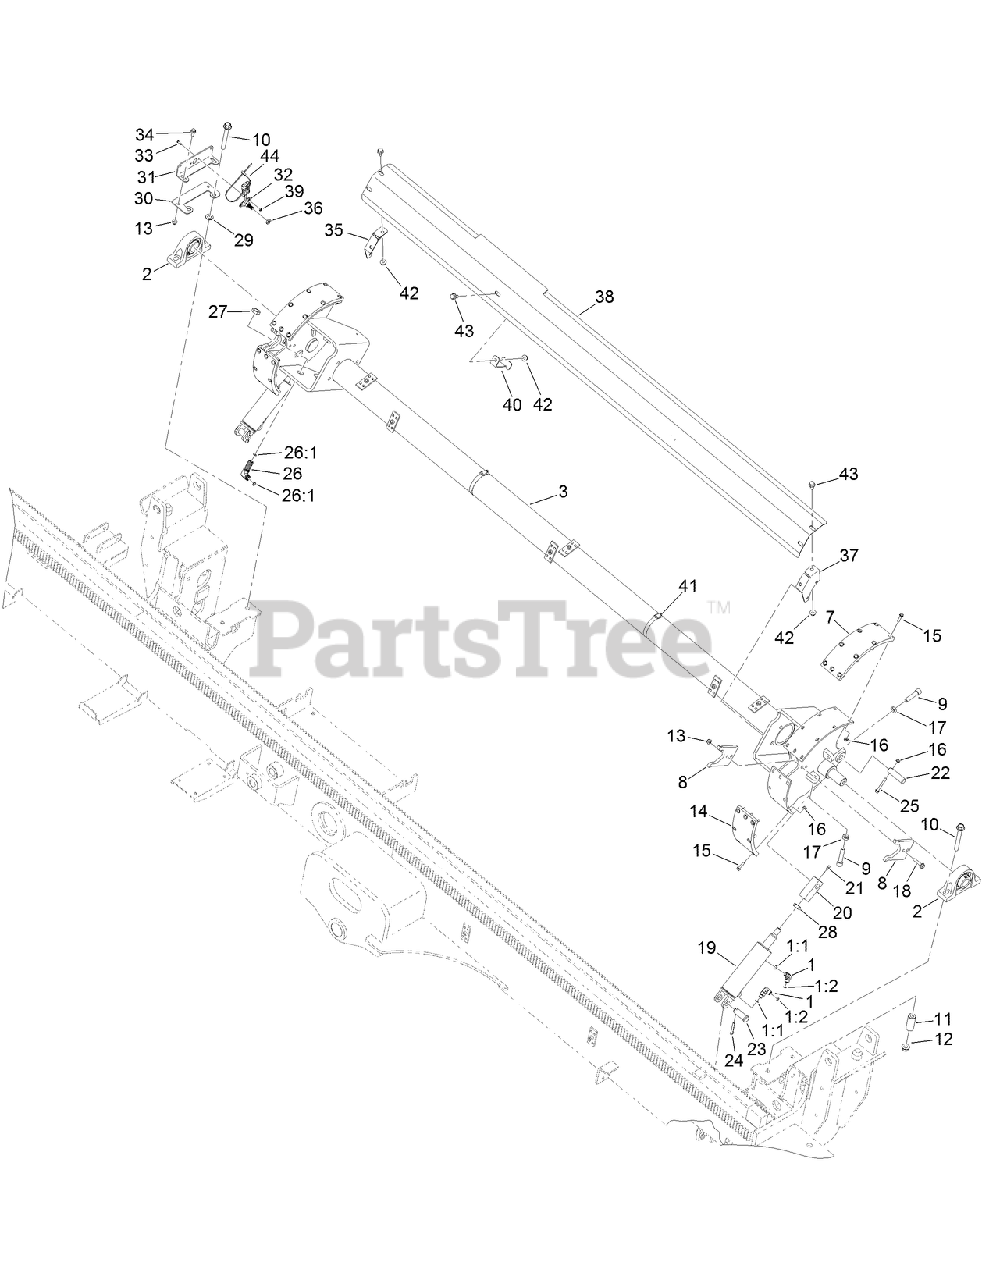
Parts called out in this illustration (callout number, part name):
1	FITTING-ELBOW, 90 DEG
1:1	O-RING
1:2	O-RING
2	BEARING-PILLOW
3	LOADER-ROD, CAM
7	PAD-WEAR, ROD LOADER
8	PLATE-GUIDE, PIPE
9	SCREW-HSH
10	SCREW-HHF
11	SPACER
12	NUT-HEX FLANGE
13	NUT-HF, NI
14	PAD-WEAR, SHORT ROD LOADER
15	SCREW-HHF
16	NUT-HF
17	NUT-JAM
18	SCREW-HHF
19	CYLINDER-HYDRAULIC
20	EYE-ROD, CYLINDER
21	FITTING-GREASE
22	PIN-STRAIGHT
23	PIN-CLEVIS
24	PIN-COTTER
25	SCREW-HHF
26	UNION-BULKHEAD
26:1	O-RING
27	NUT-LOCK
28	NUT-JAM
29	WASHER-FLAT
31	BRACKET-SENSOR, ROTARY
32	SENSOR-ROTARY
33	SCREW-SHH
34	SCREW-HHF
35	BRACKET-CAM SHIELD, BACK
36	NUT-HEX
37	BRACKET-CAM SHIELD, FRONT
38	SHIELD-CAM
39	NUT-LOCK
40	BRACKET-CAM SHIELD, SUPPORT
41	CLAMP-WORM
42	NUT-HF, NI
44	TIE-CABLE
